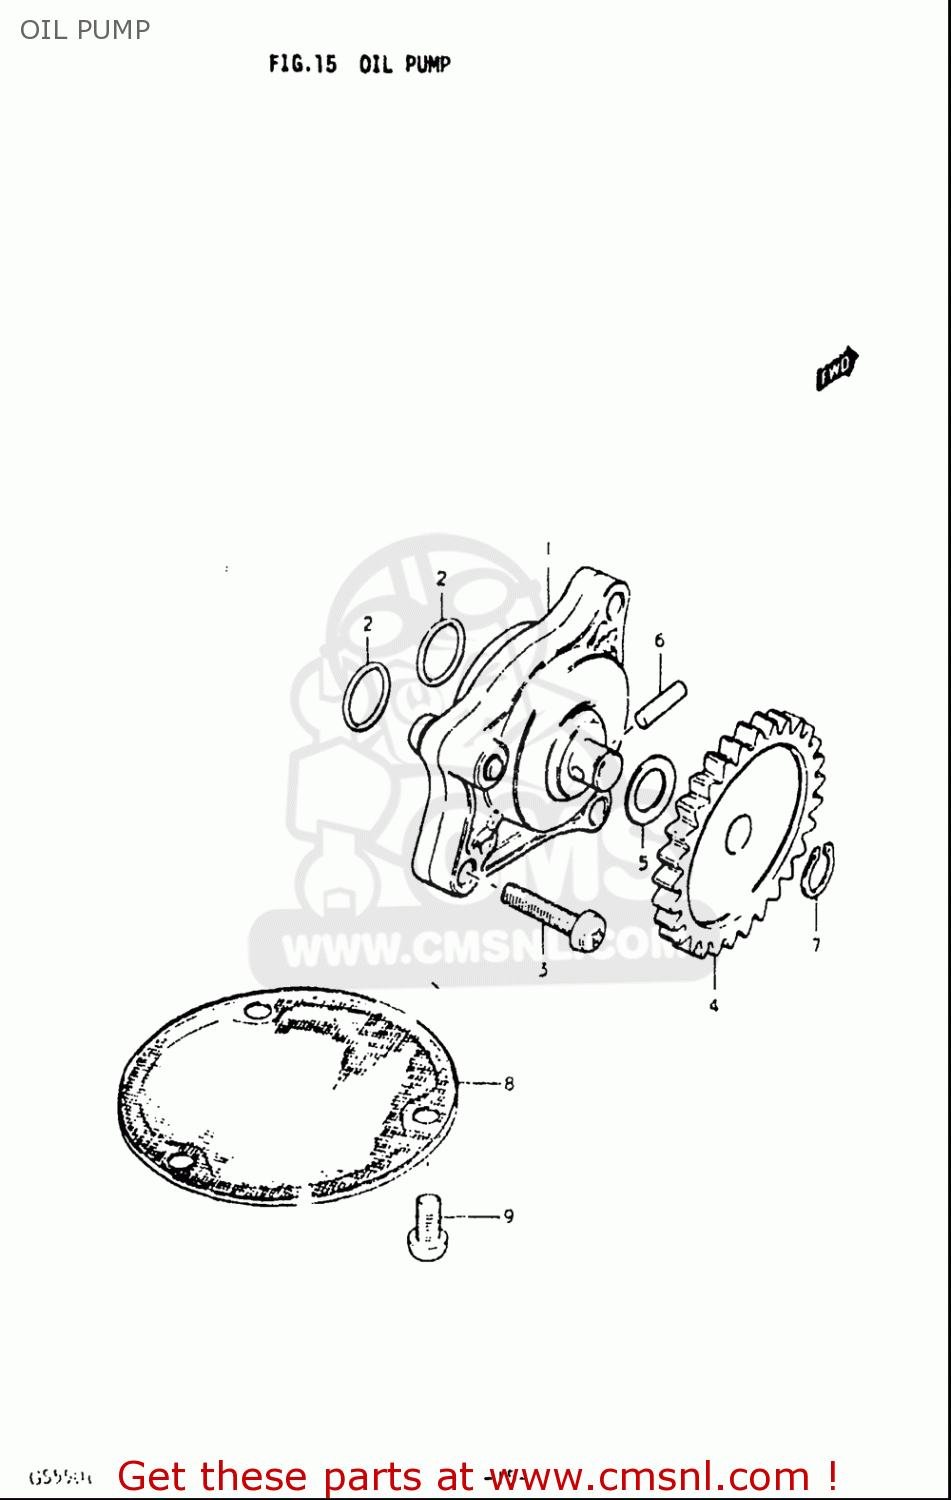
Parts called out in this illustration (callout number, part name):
1	PUMP ASSEMBLY,ENGINE OIL
2	O RING(D:1.9,ID:13)
3	SCREW
5	SHIM
6	PIN(4X15.8)
7	CIRCLIP
8	STRAINER,ENGINE OIL
9	SCREW
